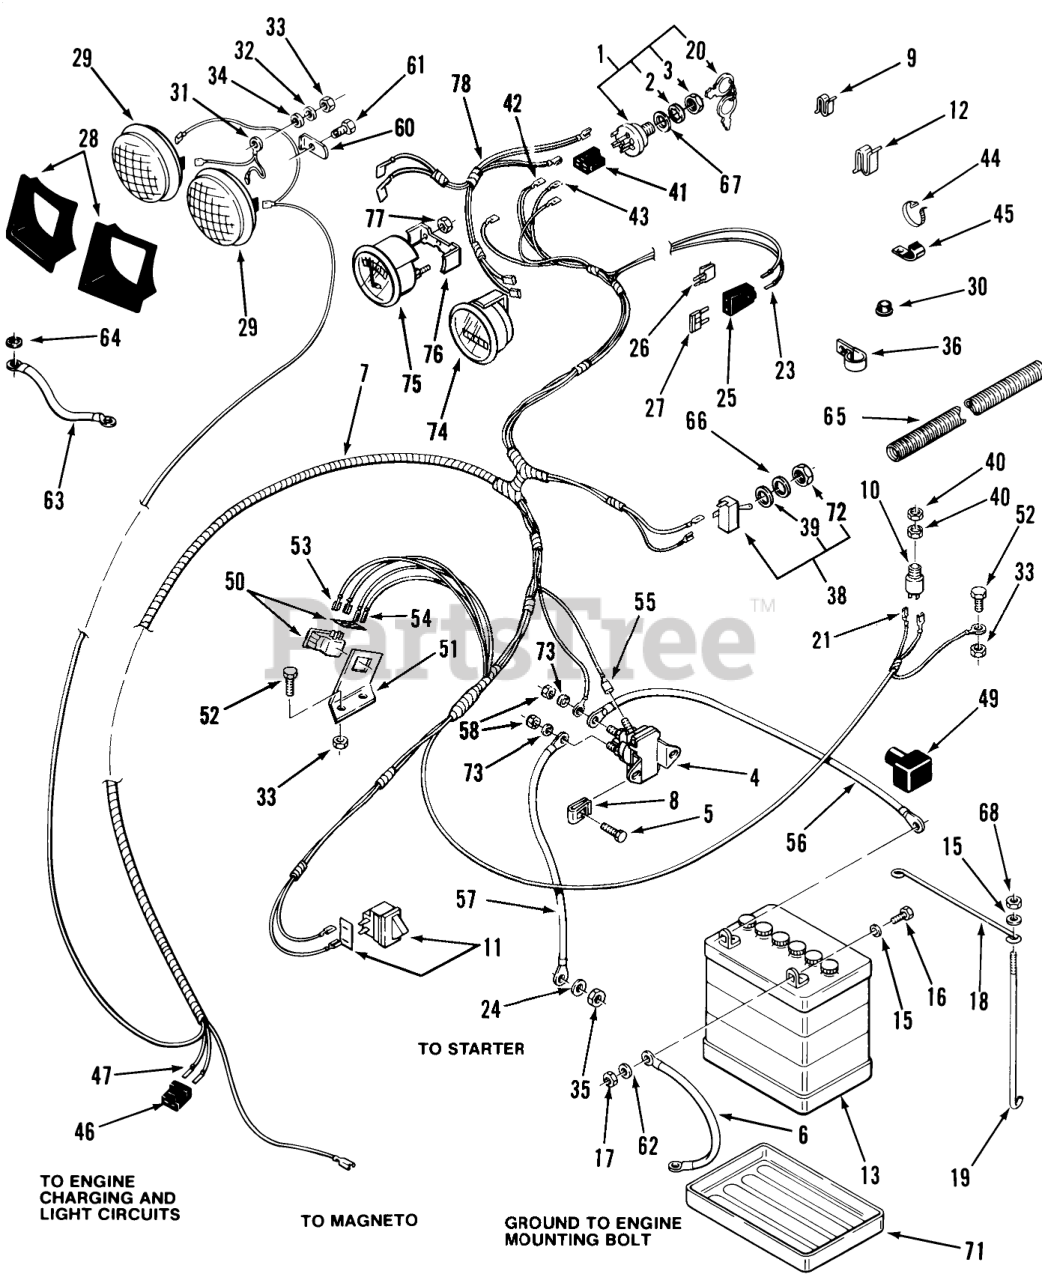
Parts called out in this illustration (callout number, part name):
1	ASSY-SWITCH IGNITION
2	LOCKWASHER
4	Solenoid
5	Screw
6	Wire
7	HARNESS-WIRING
8	Speed Nut
9	SPEED CLIP
10	SWITCH-BALL
11	SWITCH ASM (SERVICE)
12	CLIP-CABLE
13	Battery
16	Bolt
17	Nut
18	ROD-HOLD DOWN
20	Key-EL
21	Connector
23	TERMINAL-FUSE
24	Washer
25	AUTO-FUSEBLOCK TERM
27	FUSE-BLADE, 15 AMP
28	HEADLIGHT BEZEL ASSY.(SERVICE)
29	HEADLAMP
30	BUSHING-NYLON .75
31	LIGHT GROUND WIRE
33	Nut
34	Washer-Lock
35	Nut
36	CLAMP
38	SWITCH-LIGHTS
39	TAB-WASHER
40	NUT-HEX, SPECIAL
41	CONNECTOR-5 WAY-SERV
42	TERMINAL-TAB RCPT
43	Terminal
44	Cable Tie
44	PLASTIC TIE
45	CLIP
46	Conn Body Part of 7
47	Terminal
49	Boot
50	PTO Interlock Switch w/item 17
51	BRACKET-SWITCH R
52	Bolt
53	Terminal
54	Wire Terminal (Part of 1)
55	Terminal Part of 5
56	Wire
57	Starter To Solenoid Cable 23.0 in. (58.4 cm) B-115 Only
58	Nut
60	LOCK-HEADLIGHT
61	Bolt
62	Washer
63	WIRE GROUND
64	Washer-Lock
65	Conduit 216-5 Only
66	Washer
67	Washer
68	Nut
71	TRAY BATTERY
72	NUT-HEX, SPECIAL
73	Washer
74	Hourmeter 314, 417
75	Voltmeter (w/109650)
76	CLAMP MOUNTING
77	HEX NUT 10-32 E.S.
78	ASSY WIRE HARNESS
